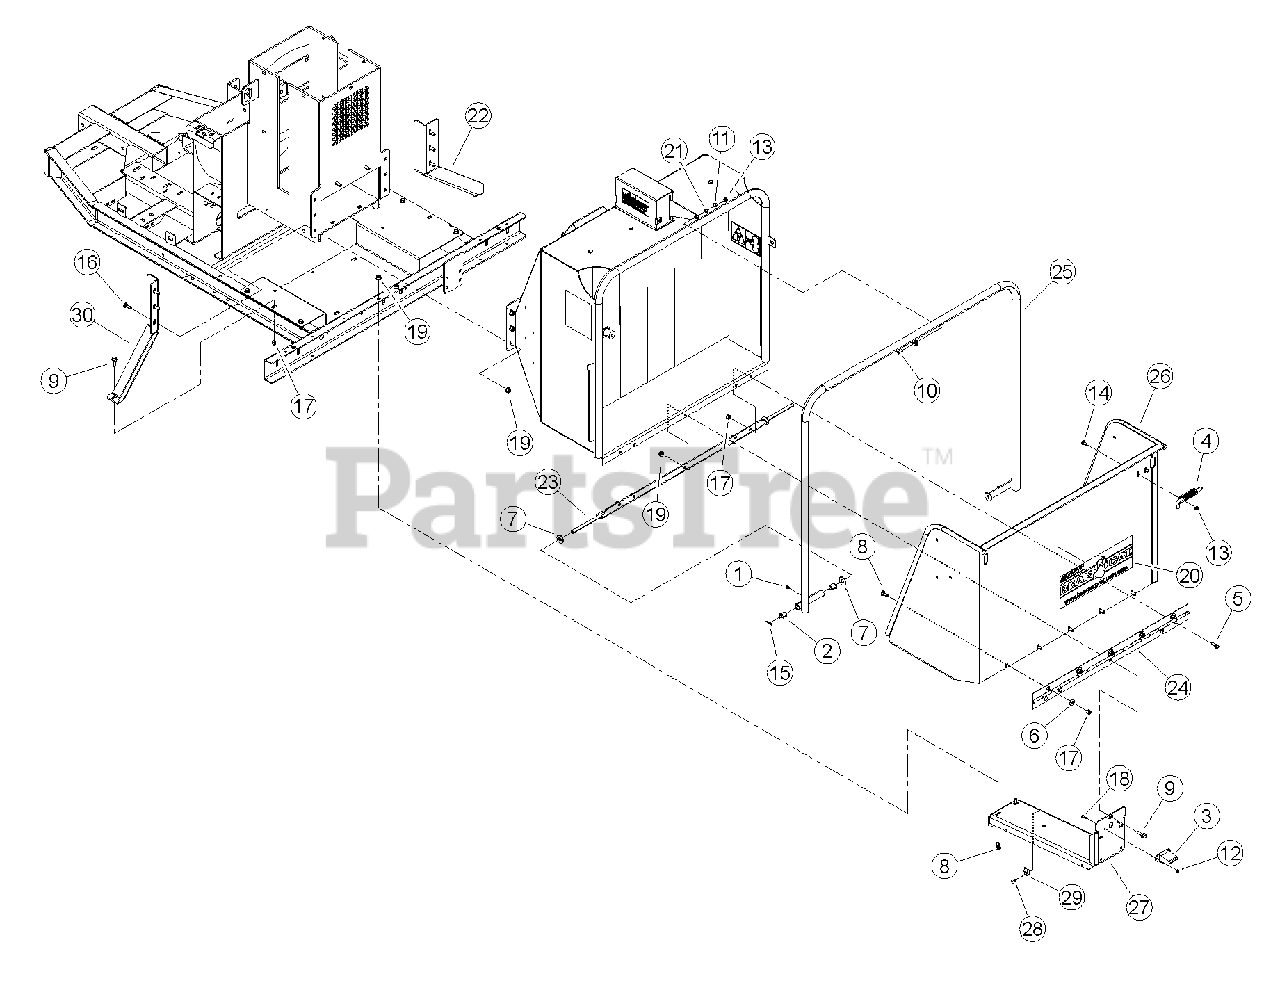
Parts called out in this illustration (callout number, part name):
1	FITTING, 1/4 SELF-TAP GREASE
2	BUSHING, 1/2 X 1 FLANGE LUBE
3	LIGHT, LICENSE PLATE
4	LATCH, RH HINGE
5	BOLT, 3/8 X 1 HEX HD GR5 ZP
6	WASHER, 3/8" FLAT ZP
7	WASHER, 1/2" FLAT ZP
8	BOLT, 3/8 X 1" GR5 CRG NC ZP
9	BOLT, 3/8 X 1-1/4 FLANGE NC
10	BOLT, 5/16 X 1" GR5 HHCS NC ZP
11	WASHER, 5/16" FLAT ZP
12	NUT, 8-32 NYLOCK
13	NUT, 5/16" NE NYLOCK ZP
14	BOLT, 5/16 X 3/4 GR5 CRG NC ZP
15	PIN, 1/8 X 1.00 ZP COTTER
16	BOLT, 3/8 X 1-1/4" GR5 CRG NC ZP
17	NUT, 3/8" NE NYLOCK ZP
18	SCREW, MCH 10-24 X 3/4" PAN HD PH ZP
19	NUT, 3/8-16 NYLOCK FLANGE
20	DECAL, BEARCAT WEB
21	SPACER, IDLER PIVOT
22	BRACKET, CHUTE SUPPORT RH
23	WELDMENT, CONTROL PIVOT
24	HINGE, EXTENSION TRAY
25	WELDMENT, CONTROL ARM
26	WELDMENT, EXTENSION TRAY
27	ASSEMBLY, CHUTE/SPARE SUPPORT 6 IN SERVICE PART
28	RIVET, AL BLIND 1/4 X 3/4 DOME HEAD
29	CLAMP, CABLE MOUNT
30	WELD, PLATE LH SUPPORT
